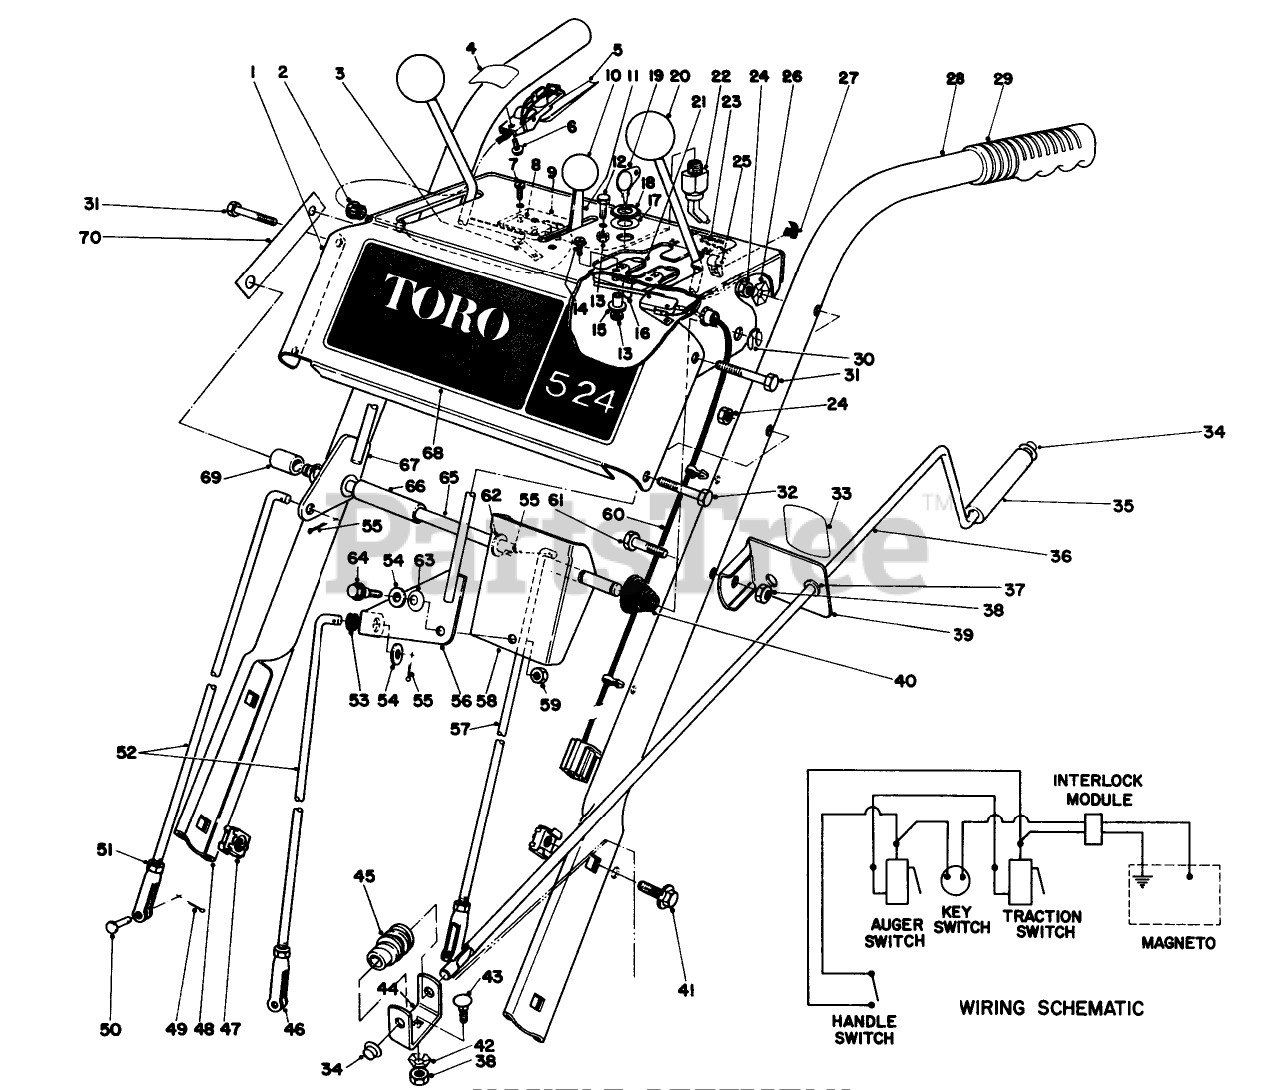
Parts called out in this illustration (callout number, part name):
2	BUSHING NYLON
3	NUT-SPEED
6	SCREW
7	SCREW-SPH
8	SWITCH-MICRO
14	Screw
15	INTERLOCK SPACER
16	INTERLOCK SPRING
17	WASHER-LOCK
18	NUT-HH
24	NUT-LOCK, CONE
30	RING-CLIP
31	SCREW-HH
32	SCREW-HH
34	NUT-PUSH
35	GRIP-CONTROL, CHUTE
38	NUT-LOCK, NI
40	CONICAL SPRING
41	SCREW-HHF
42	WASHER-LOCK
43	BOLT-CARR
44	BRACKET-WORM
45	GEAR-WORM, CHUTE
49	PIN-COTTER
50	PIN-CLEVIS
51	NUT-HJ
53	GROMMET-RUBBER
54	WASHER-FLAT
55	PIN-COTTER
59	NUT-LOCK, CONE
61	SCREW-HH
62	WASHER-FLAT
65	PIVOT ROD
66	SHIFT LEVER SPACER
67	LEVER WA
69	AUGER LEVER SPACER
